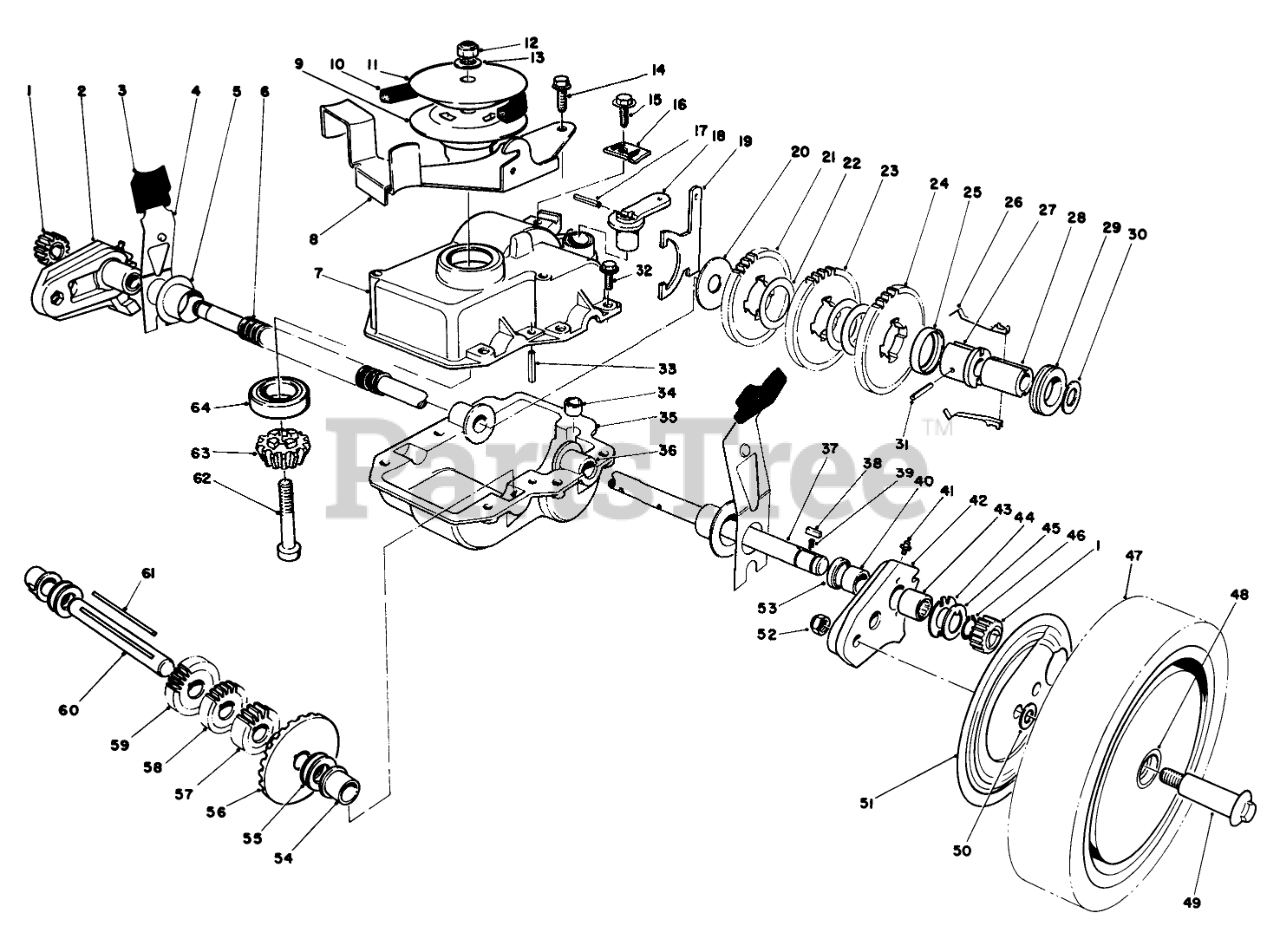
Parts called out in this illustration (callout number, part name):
1	GEAR-PINION
2	Pivot Arm Assembly-R.H. (Incl. Ref. #40, 41, 43 & 53)
3	KNOB-ARM
4	SPRING ARM ASM SP
5	CAP-END
6	CONDUIT-CONVOLUTED, SPLIT
7	Case-Upper
8	BELT GUIDE BRKTB
9	PULLEY-LOWER HALF
10	V-BELT
11	PULLEY-UPPER HALF
12	NUT-LOCK, NI
13	WASHER-FLAT
14	SCREW
15	SCREW-HWHTF
16	Cable Clamp
17	PIN-COIL
18	LEVER-SHIFT
19	Shift Yoke
20	WASHER
21	GEAR-38T
22	WASHER
23	GEAR-42T
25	RETAINER-KEY
26	KEY-SHIFT
27	SLEEVE-GEAR
28	SLEEVE
29	COLLAR-SHIFT
30	WASHER-PLAIN
31	PIN-SPRING
32	SCREW-HWHTF
33	ROLL PIN 3/16 X 1 IN
34	BUSHING-YOKE
35	LOWER GEAR CASE CAST
36	Bushing-Output Shaft
37	Output Shaft
38	KEY RECTANGULAR
39	SPRING-COMPRESSION
40	BUSHING
41	FITTING-GREASE
42	Pivot Art Assembly-L.H. (Incl. Ref. #40, 41, 43 & 53)
43	BEARING-ROLLER
44	INNER THRUST WASHER
45	WASHER-THRUST, OUTER
46	RING-RETAINING
47	Wheel, Tire & Gear Assembly (Incl. Ref. #48)
48	BUSHING
49	WHEEL BOLT
50	WASHER
51	WHEEL COVER
52	NUT-LOCK
53	SEAL-OIL
54	BUSHING
55	WASHER-THRUST
56	BEVEL GEAR
57	GEAR-12T
58	GEAR-14T
59	GEAR-18T
60	INTERMEDIATE SHAFT
62	Screw-Socket Hd
63	BEVEL PINION
64	BEARING-BALL
